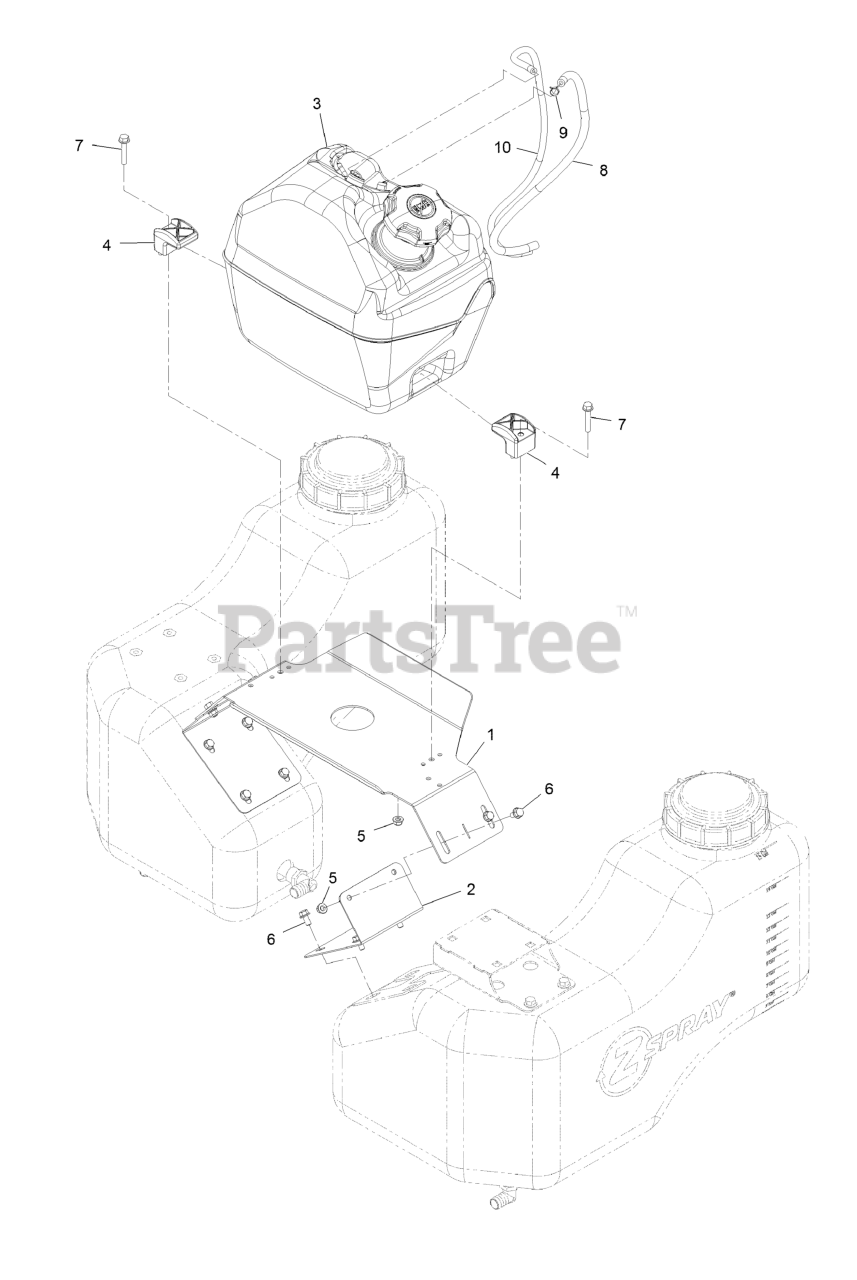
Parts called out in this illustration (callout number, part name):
1	Support-Fuel Tank
2	BRACKET-SUPPORT, GAS TANK
3	Fuel Tank ASM, 5 Gal
5	Nut-Hex Flange
6	Screw-HHF
7	Screw-HHF
8	HOSE-FUEL
9	CLAMP-HOSE
10	HOSE-FUEL
